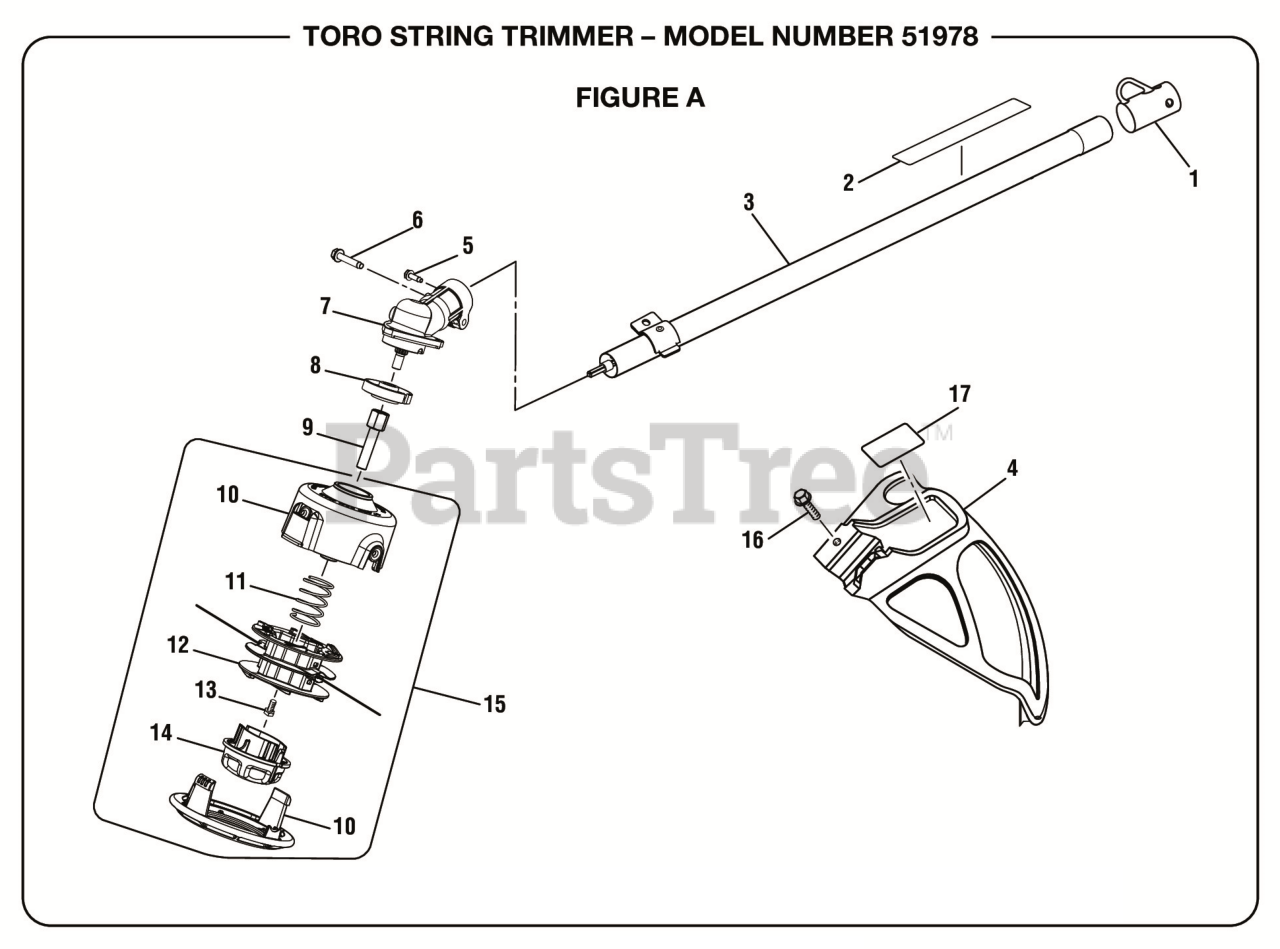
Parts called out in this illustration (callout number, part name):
1	Hanger Cap
2	Warning Icon Label
3	Straight Shaft Assembly
4	Grass Deflector Assembly
5	Screw w/Washer (10-24 x 5/8 in., Hex Hd. T.F.)
6	Screw (1/4-20 x 1-1/4 in., Hex Washer Hd. S.T.)
7	Gear Head Assembly
8	FLANGED WASHER
9	Trimmer Head Shaft Adaptor
10	Stringhead Housing
11	Compression Spring
12	Spool w/ Line (.095)
13	Screw (5/16 x 1/2 in., Left Hand)
14	Bump Knob
15	Trimmer Head Assembly (.095)
16	SCREW (#1/4-20 X 1-1/4 in. HEX WASHER HD.)
17	Grass Deflector Label
